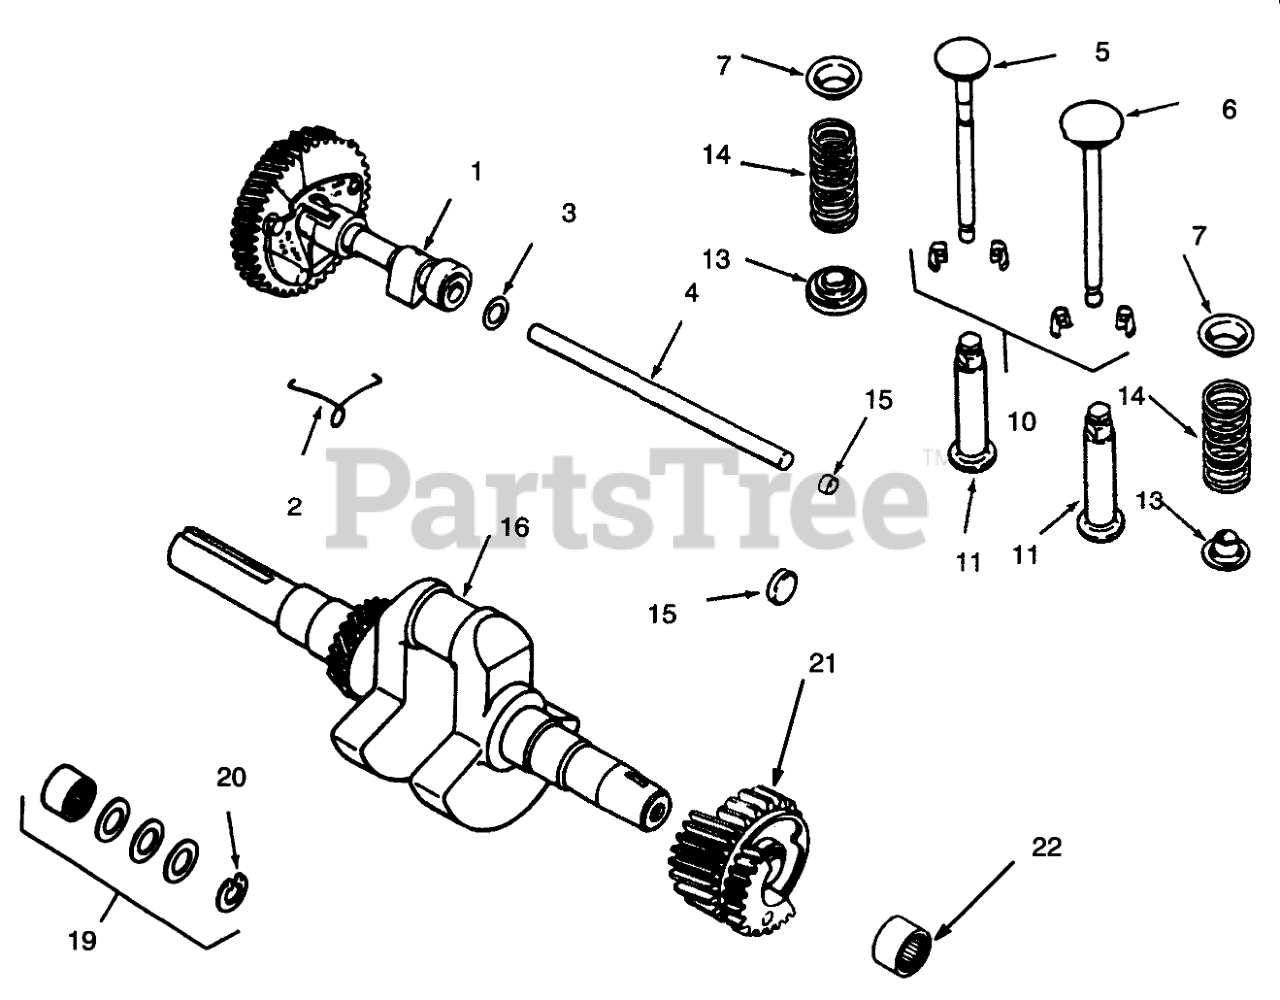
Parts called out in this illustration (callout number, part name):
1	Camshaft Assy (Incl. Ref. #2)
2	Spring
3	Spacer .005
4	Camshaft Pin
5	Valve-Exhaust
6	Valve-Intake
7	UpperSpring Retainer
10	Kit-Retainer
11	Tappet
13	Rotator-Valve
14	Spring
16	Kit-Crankshaft (Includes Flywheel Hdwr.)
19	Kit-Spacer (Incl. Ref. #20)
20	Retainer
21	Gear Assembly (Incl. Ref. #22)
22	Bearing-Needle
